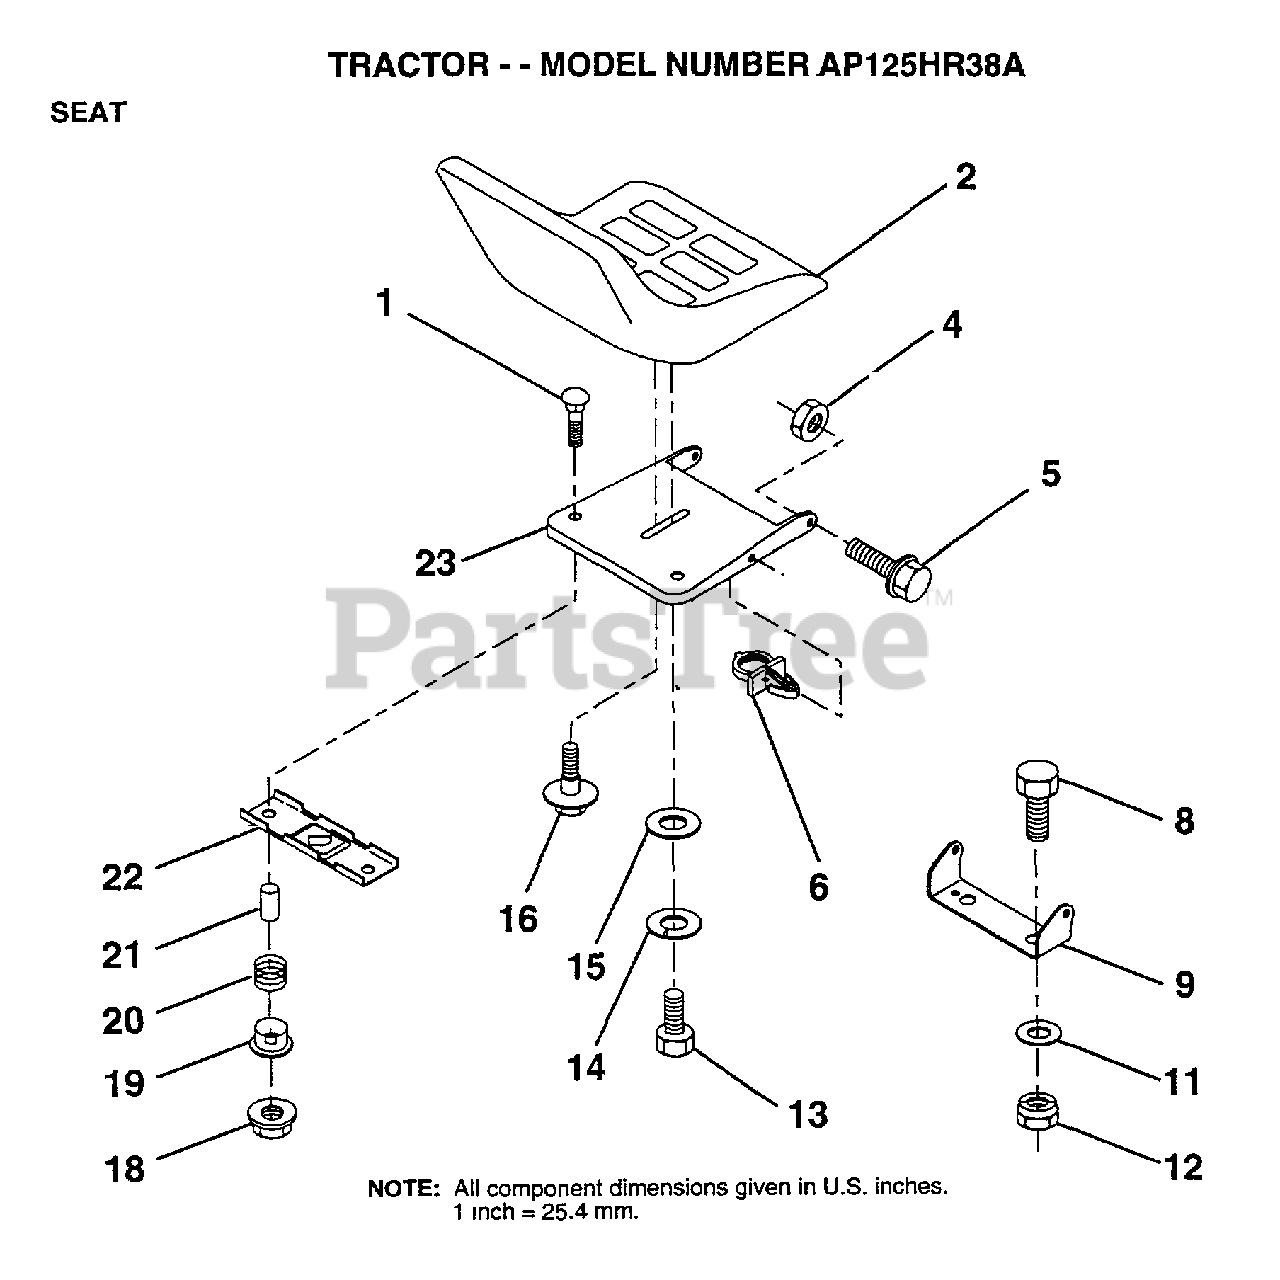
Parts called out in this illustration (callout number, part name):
4	NUT
5	BOLT.SHLD.5/16-18
6	CLIP.PUSH-IN.HING
8	BOLT
9	BRACKET PVT SEAT
11	WASHER
12	NUT
13	BOLT
14	LOCKWASHER
15	WASHER
16	"BOLT,SHOULDER"
19	BUSHING
20	SPRING
21	SPLIT SPACER
22	BRKT SWITCH
